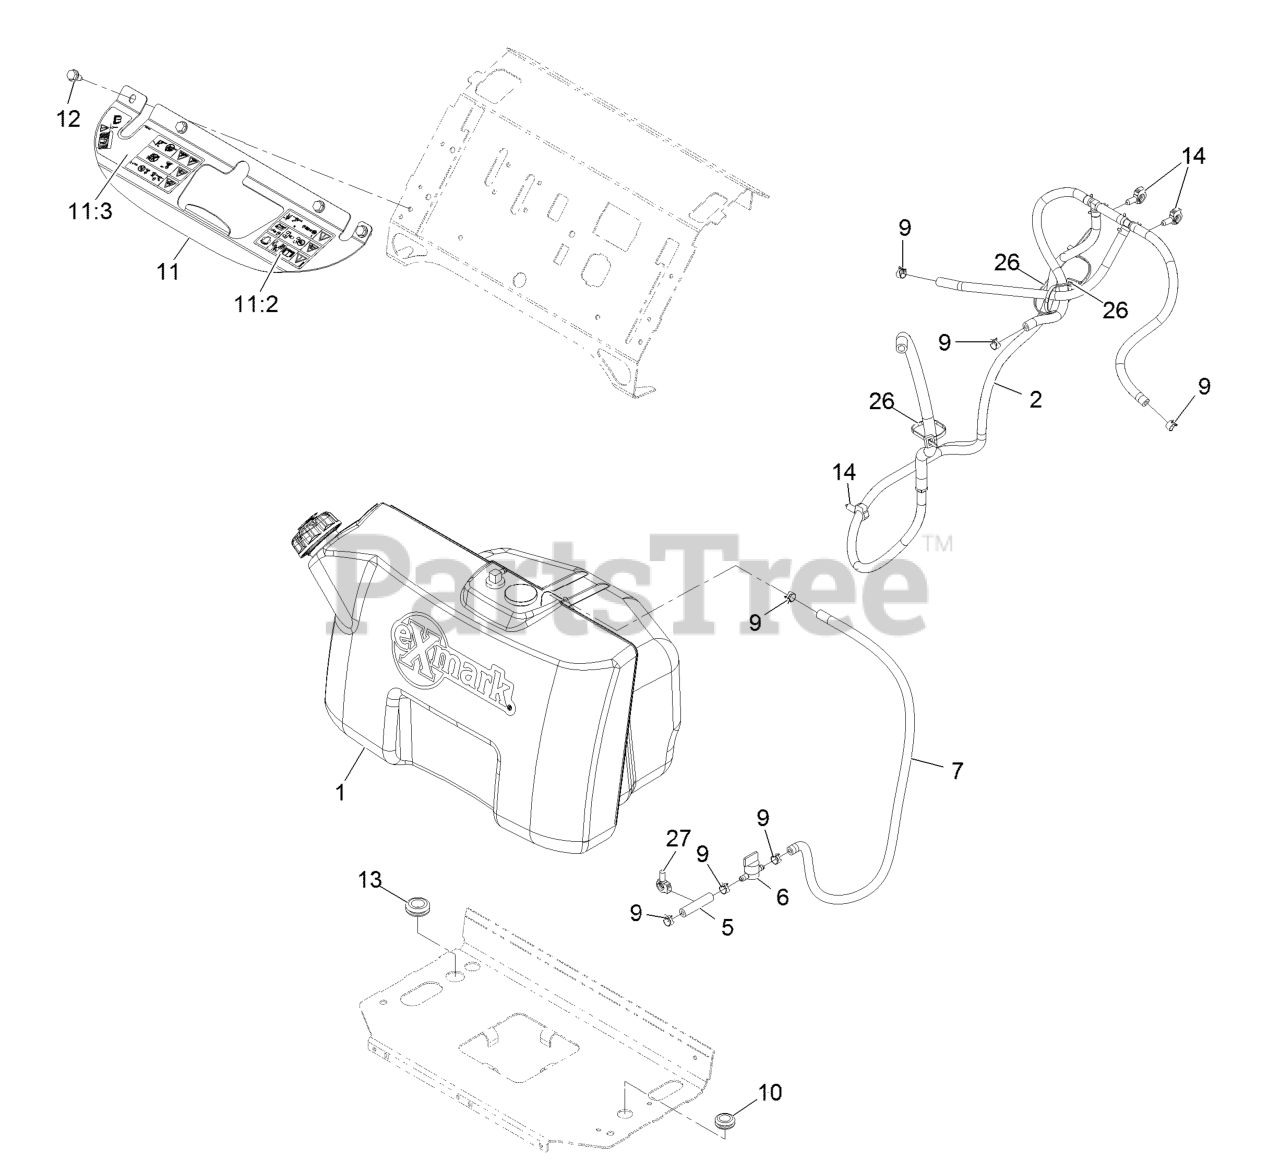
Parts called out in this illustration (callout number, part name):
2	VENT ASM
5	HOSE-FUEL
6	VALVE-FUEL
7	HOSE-FUEL
9	CLAMP-HOSE
10	GROMMET
11	BRACKET-TANK
11:2	DECAL-WARNING LH
11:3	DECAL-WARNING RH
12	Screw-HWH 5/16-18 X 3/4 Tf
13	GROMMET
14	CLIP-HARNESS
26	TIE-CABLE
27	CLIP-HARNESS
